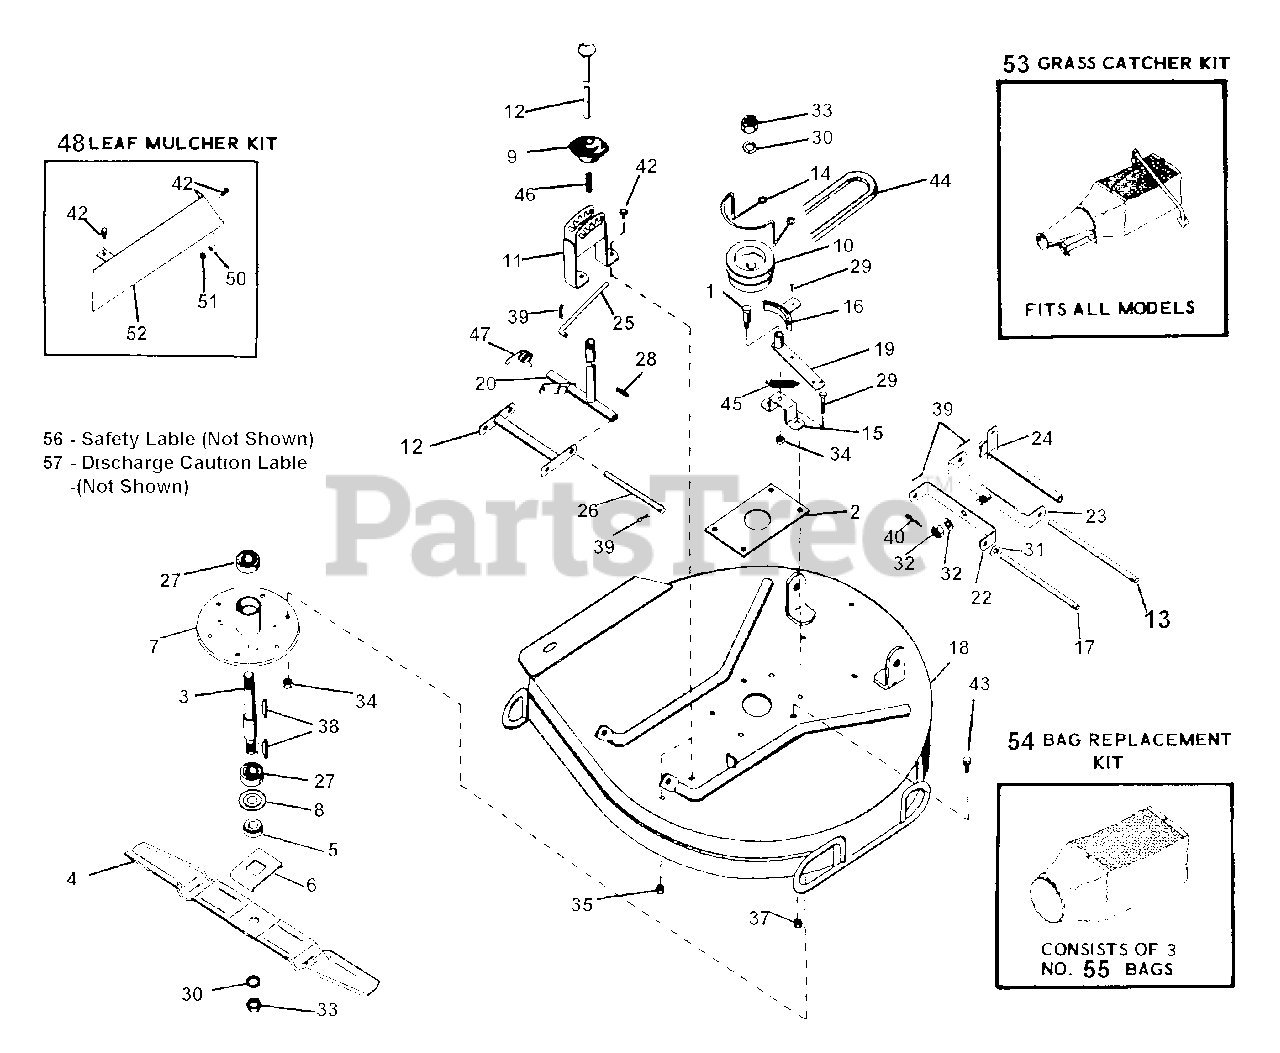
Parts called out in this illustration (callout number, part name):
1	SHOULDER BOLT .50 X 1.75
3	MOWER SPINDLE
4	BLADE, MOWER
5	RETAINER HUB
6	BLADE TRAY
7	SPINDLE HOUSING
8	BEARING SLINGER
9	SHIFT BALL
10	MOWER SHEAVE
11	MOWER HGHT QUAD
12	HGHT CNTL PLNGR
13	REAR BRACKET PIN
14	MOWER BELT FINGER
15	BLADE BRAKE SUPPORT
16	BLADE BRAKE
17	HANGER PIN
18	MOWER PAN
19	BLADE BRAKE ARM
20	HGHT CNTL ARM
21	FLOATING LINK
24	REAR RAISING BRACKET
25	HGHT LINK ROD
26	ADAPTER PIN
27	BRG-BALL .751X1.78X.61
28	PIN-ROLL .250X1.25
29	BLT-HEX .38-16X1.00 PL
30	WSHR-LK .750X.188 MED PL
31	WSHR-FL-STL .531X1.062X.095 PL
32	WSHR-FL-STL .630X1.005X.062 PL
33	NUT-JAM .75-10 PL
34	NUT-LK-CTR .375-16 GR A PL
35	NUT-LK .312-18 GR A PL
36	NUT-JAM-SL .625-18
37	NUT-LK-FLG .250-20 PL
38	KEY-WDRF .188X.75X.313 SAE 9
39	PIN-COTR .12X1.0 PL
40	PIN-COTR .12 X 1.25 PL
41	RVT .25X.50 RH ST
42	BLT-SERHFWH .31-18X.50 PL
43	SCR-SLTR-SERNK .25-20X.62 PL
44	BELT,5L RAW LAMINATED
45	SG-TENS .072X.51X5.31 WLD 25
46	SG-COMP ??X.44X?? WLD 10
47	SG-TORS .162X.75X.648
48	COVER, TRANSMISSION
49	BLT-SERHFWH .31-18X.50 PL
50	WSHR-LK .312X.097 PL HVY
51	NUT-HEX .312-18
52	LEAF MULCHER
53	PADDLE, CLUTCH - LH, COMPACT
54	WELDMENT, SPEED CONTROL ARM
55	BAG
56	SAFETY LABEL
57	DISCHARGE CAUTION LABEL
